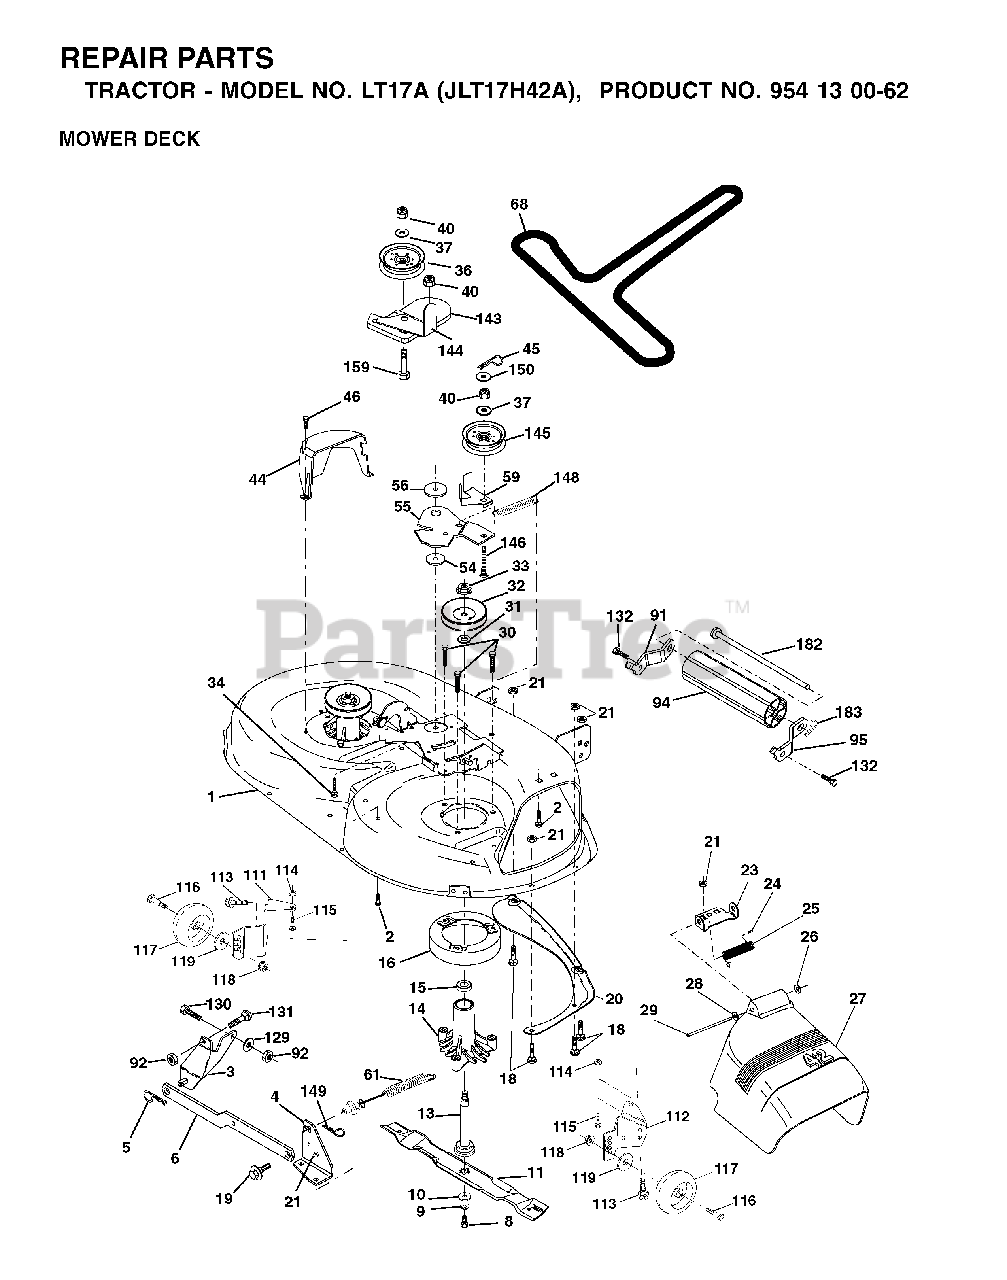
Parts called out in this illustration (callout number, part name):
1	42" DECK KIT
2	BOLT
3	BRKT ASM SWAY BAR
4	BRACKET SWAY BAR 42" DECK
5	RETAINER-SPRNG RB
6	BAR SWAY DECK
8	BLADE BOLT
9	LOCKWASHER
10	WASHER.BLADE
11	BLADE 42"
13	SHAFT ASM VENT
14	HSG MANDREL
16	STRIPPER, MWR ROUND
18	BOLT
19	BOLT SHD 5/16-18
20	BAFFLE.VORTEX
21	LOCKNUT
23	BRKT, DEFL. MOWER
24	CAP-SLEEVE LT
25	SPRING TORSION
26	NUT PUSH M
27	SHIELD DEFLECTOR
28	WASHER
29	ROD.HINGE
30	SCREW, WASHER HEAD
31	WASHER
32	PULLEY/MANDREL
33	NUT, FLG TOPLOCK 9/16"
34	BOLT
36	FLAT IDLER PULLEY
40	LOCKNUT
44	GUARD MANDREL LH BLACK
45	RETAINER M
46	SCREW.1/4-20X5/8
54	HARDENED WASHER
55	ARM IDLER 42" MOWER LT/YT
56	SPACER.RETAINER.MOWER
59	GUARD, BELT
61	SPRING EXT ELEC CLUTCH
91	BRACKET ASM NOSEROLLER LH
92	NUT
94	NOSE ROLLER
95	BRACKET ASM NOSEROLLER RH
111	BRACKET, WHEEL
112	BRACKET, WHEEL
113	SCREW.3/8-16X.625
114	NUT
115	BOLT
117	WHEEL.GAUGE.STANDARD
118	LOCKNUT
119	WASHER
129	WASHER
130	BOLT
131	BOLT D
132	SCREW 3/8-16X3/4
143	BRACKET, ARM IDLER
144	KEEPER.BELT.42".CLUTCH.CABLE
145	PULLEY
146	BOLT, CARRIAGE IDLER BLACK
148	IDLER RETURN SPRING
149	SPRING.RETAINER.YELLOW.ZINC
150	WASHER PM
159	BOLT
182	ROD ROLLER NOSE STANDARD
183	SPRING RETAINER
